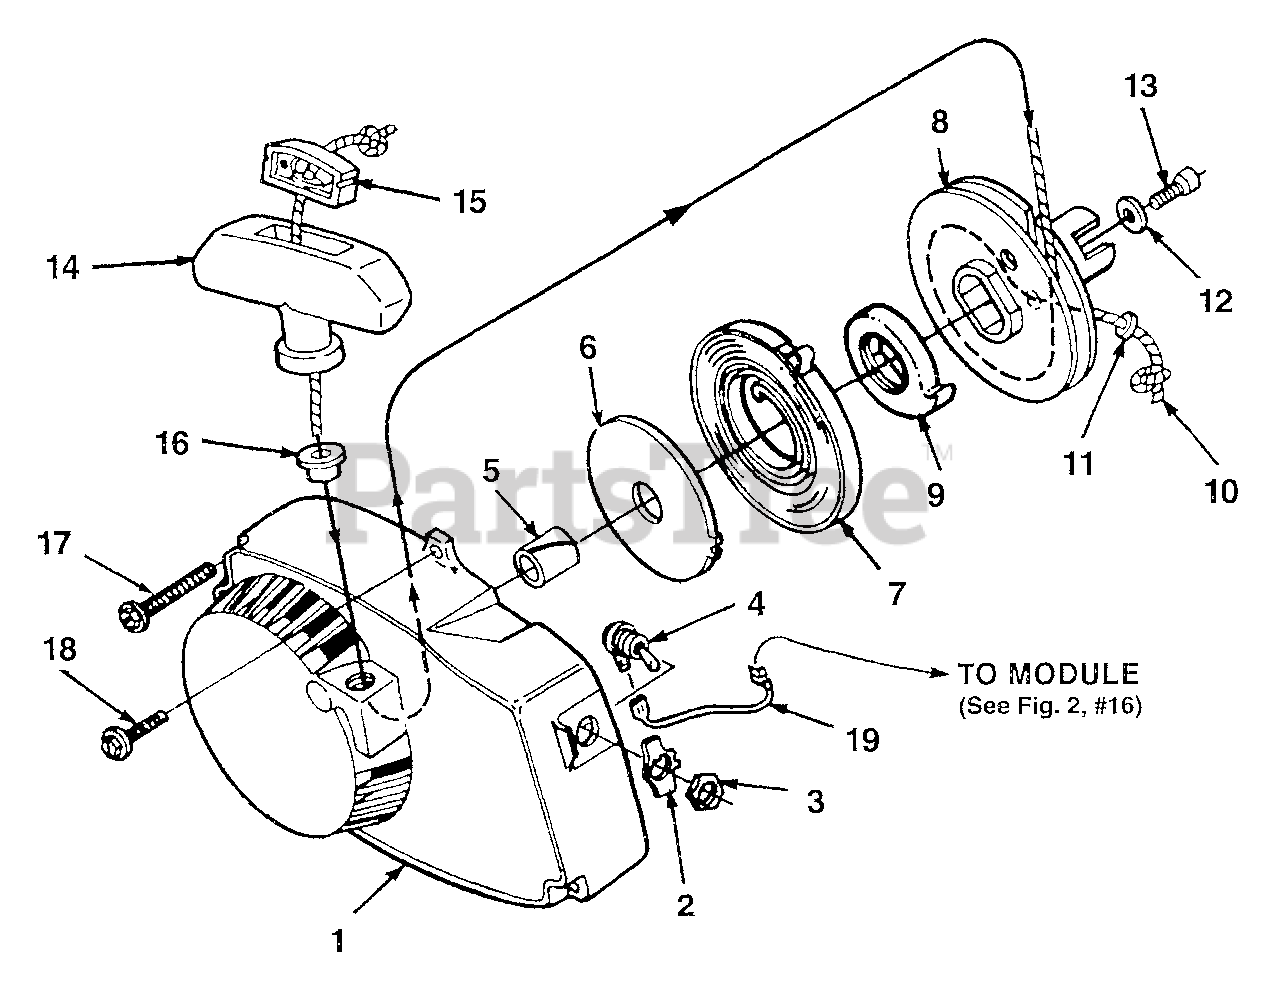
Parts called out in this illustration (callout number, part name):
2	PLATE- On & Off
3	NUT- Hex Locking
4	SWITCH & LEAD
5	BUSHING-Starter
6	SHIELD-Spring (inner)
7	SPRING- Recoil
8	PULLEY-Starter
9	BUSHING-Spring
10	ROPE-Starter (48")
11	WASHER-Flat Nylon
12	WASHER-Retainer
13	SCREW-Hex (10-32 X 1/2")
14	GRIP-Starter Rope
16	BUSHING-Rope
17	SCREW-Hex (12-24 X 11/16)
18	SCREW-Hex (12-24 X 9/16)
